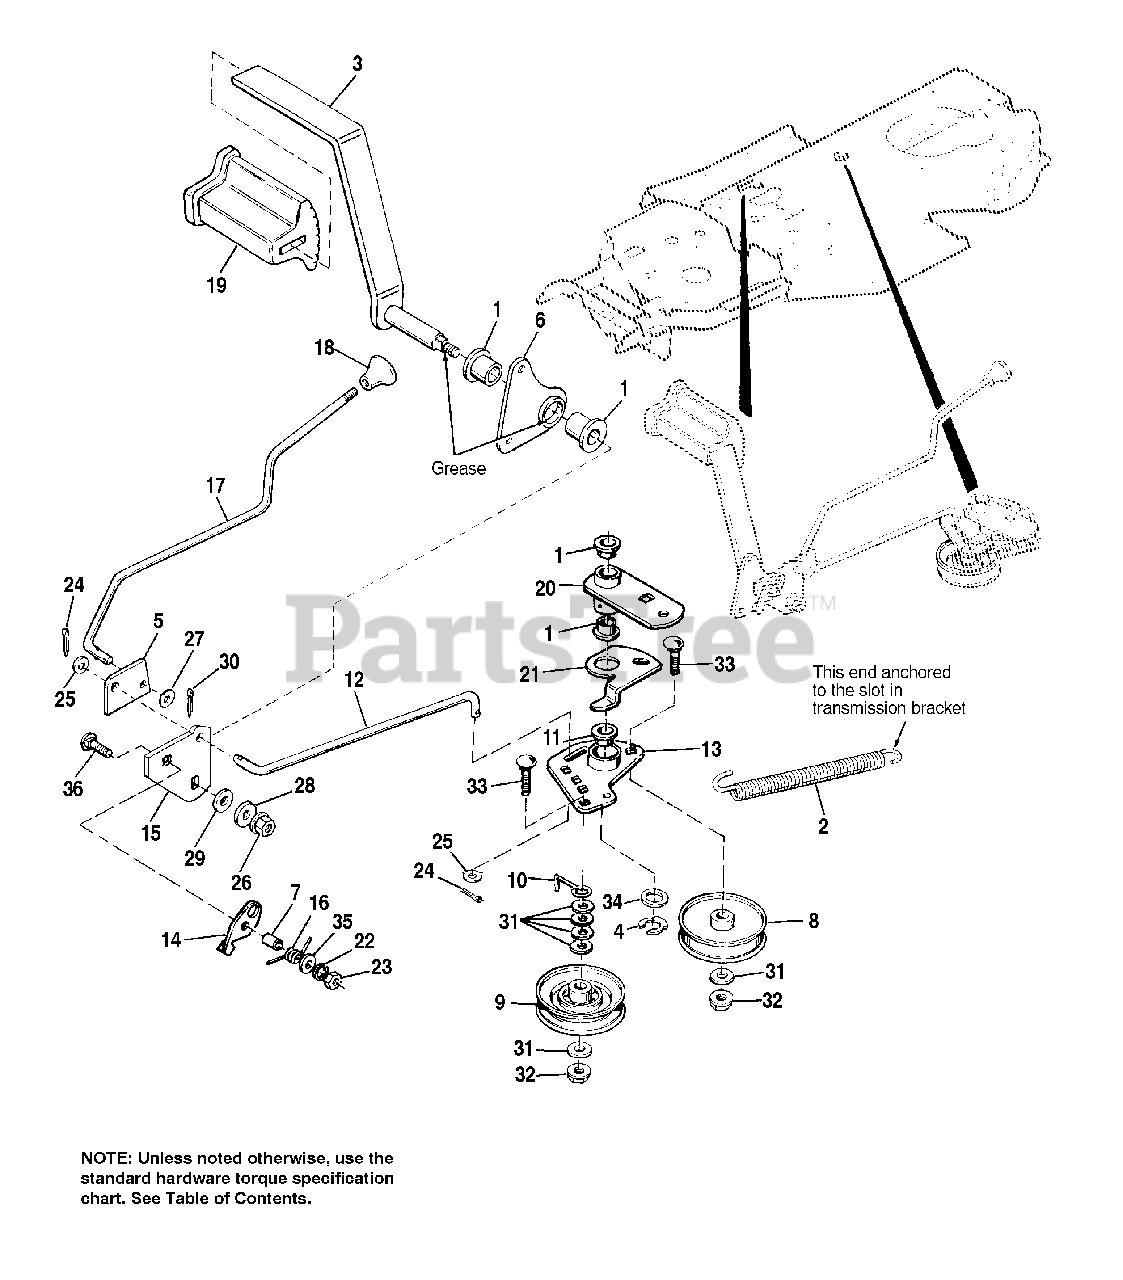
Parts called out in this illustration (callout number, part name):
1	BUSHING, Plastic
2	SPRING, Drive
3	BRAKE PEDAL ASSY.
4	KLIP RING, 5/8
5	CAM, Parking Brake
8	PULLEY, Idler, Flat
9	PULLEY, "V"
11	BUSHING, Plastic
12	ROD, Clutch, 5/16 Dia.
13	IDLER ARM ASSY.
14	ACTUATOR, Switch
15	ARM, Foot Pedal
16	SPRING, Tension
17	ROD, Parking Brake
18	KNOB, Plastic
19	PAD, Foot Pedal
20	PIVOT ASSY., Shift
21	LEVER, Lockout
22	LOCKWASHER, 5/16
23	NUT, Hex, 5/16-18
24	COTTER PIN
25	WASHER, Plain, 5/16
26	NUT, Hex , ESNA, 3/8-16
27	WASHER, Plain, 9/32
28	WASHER, 13/32 x 1-1/2 x 1/16
29	WASHER
30	COTTER PIN
31	WASHER, Plain, 13/32
32	NUT, Flange, Whizlock, 3/8-16
33	CAPSCREW, 3/8-16 x 1-3/4
34	WASHER, 5/8
35	WASHER, 5/8
36	CARRIAGE BOLT, 5/16-18 x 1-1/4
